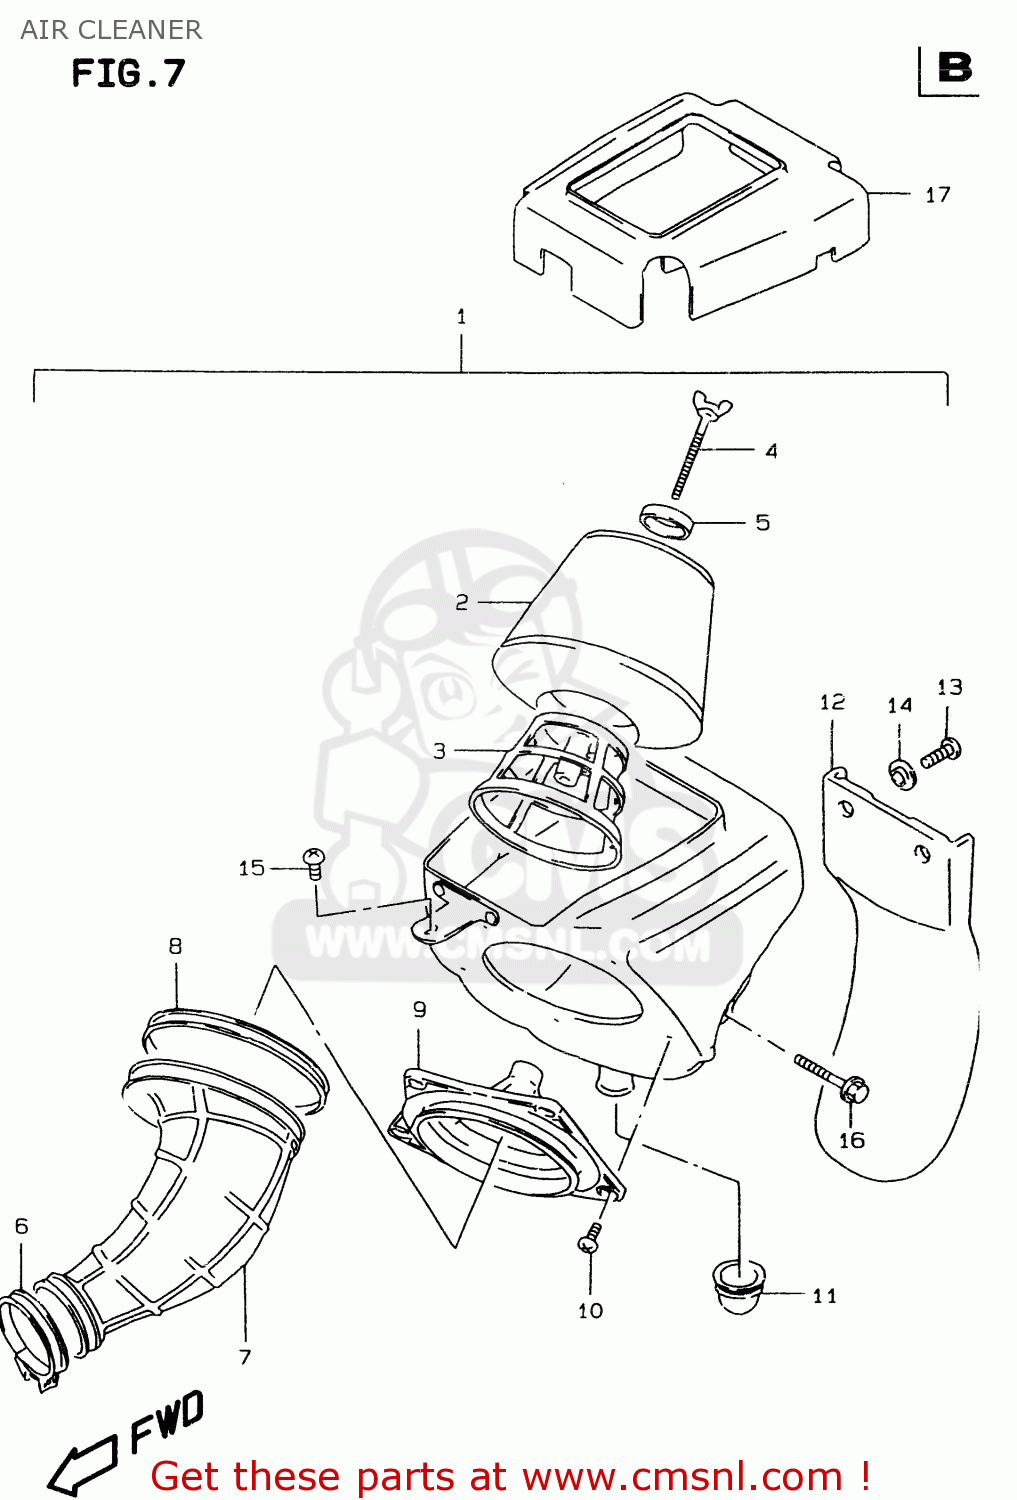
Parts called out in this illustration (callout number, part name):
1	CLEANER ASSY,AIR
2	FILTER ASSY
3	HOLDER
4	BOLT,WING
5	WASHER,AIR CLEANER
6	CLAMP
7	TUBE,OUTLET
8	CLAMP
9	BASE,FILTER
10	SCREW L:12
11	HOSE,AIR CLEANER DRAIN
12	GUARD,MUD
13	SCREW
14	COLLAR
15	SCREW 6X12
16	BOLT
17	MUD GUARD,B
